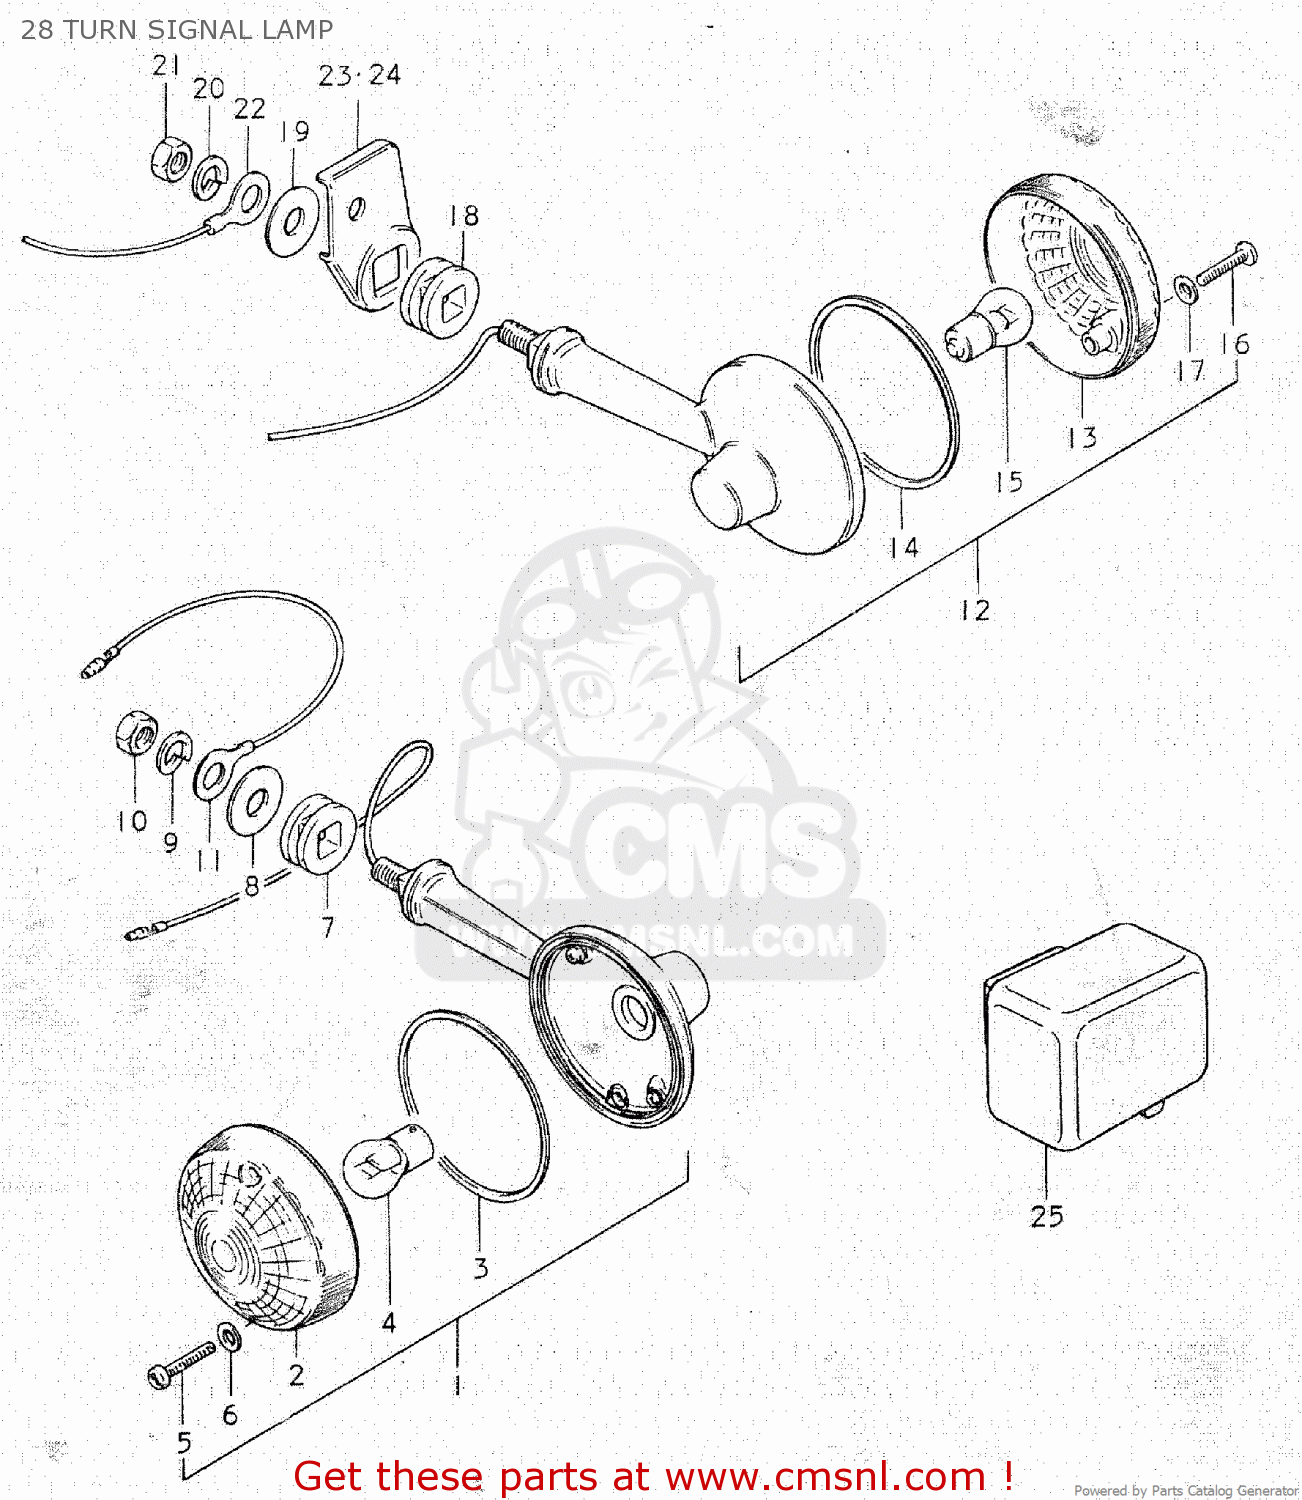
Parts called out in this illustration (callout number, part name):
1	LAMP ASSEMBLY,FRONT TURN SIGNAL
2	LENS
3	GASKET (NAS)
4	BULB(12V23W,STANLEY,A4577A)
5	SCREW
6	GASKET (NAS)
7	CUSHION
8	WASHER (10.5X30X2.3)
9	LOCK WASHER
10	NUT
11	WIRE
12	LAMP ASSEMBLY,FRONT TURN SIGNAL
13	LENS
14	GASKET (NAS)
15	BULB(12V23W,STANLEY,A4577A)
16	SCREW
17	GASKET (NAS)
18	CUSHION
19	WASHER (10.5X30X2.3)
20	LOCK WASHER
21	NUT
22	WIRE
23	BRACKET,RR TURNSIGNAL LAMP,R
24	BRACKET,RR TURNSIGNAL LAMP,L
25	RELAY,TURN SIGNAL
